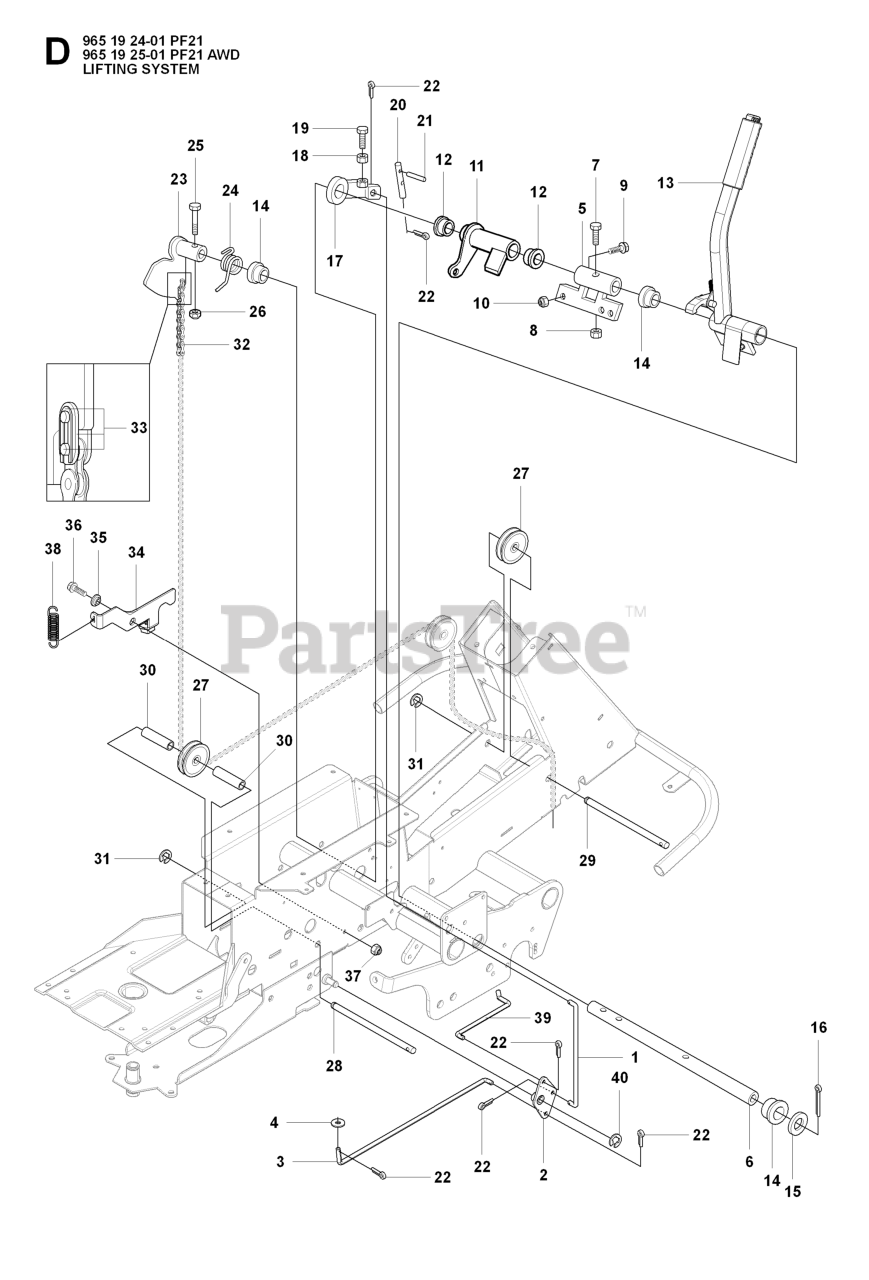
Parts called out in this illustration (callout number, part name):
9	SCREW M6S 8X25
10	NUT
12	BEARING FLANGE
13	LIFTING LEVER ASSY
14	BEARING FLANGE
17	LEVER CLUTCH
18	NUT
20	RP PIN
35	WASHER
36	BOLT
37	LOCKNUT M8
40	RETAINING RING
